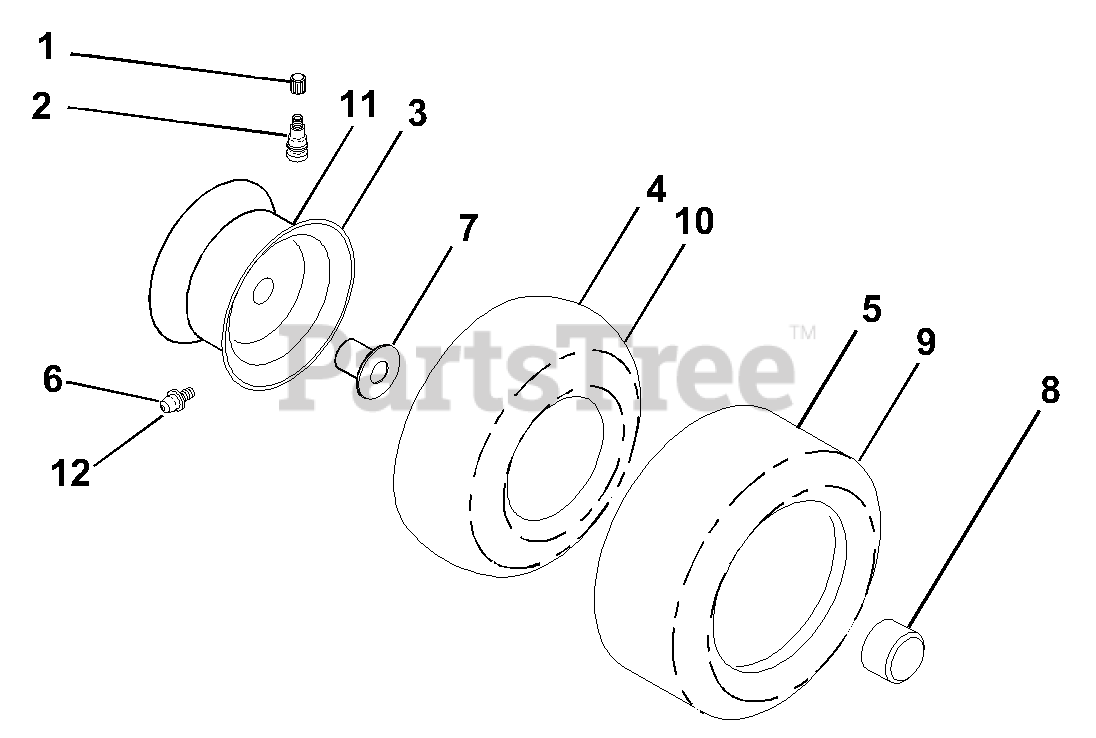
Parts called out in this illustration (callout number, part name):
1	Cap, Valve, Tire
2	Stem, Valve
3	Rim Assembly, Front
4	Tube, Front
5	Tire, Front
6	Fitting, Grease
7	Bearing, Flange
8	Cap, Hub, Axle Blk.
9	Tire,Rear
10	Tube, Rear
11	Rim Assembly, Rear
12	Fitting Grease
